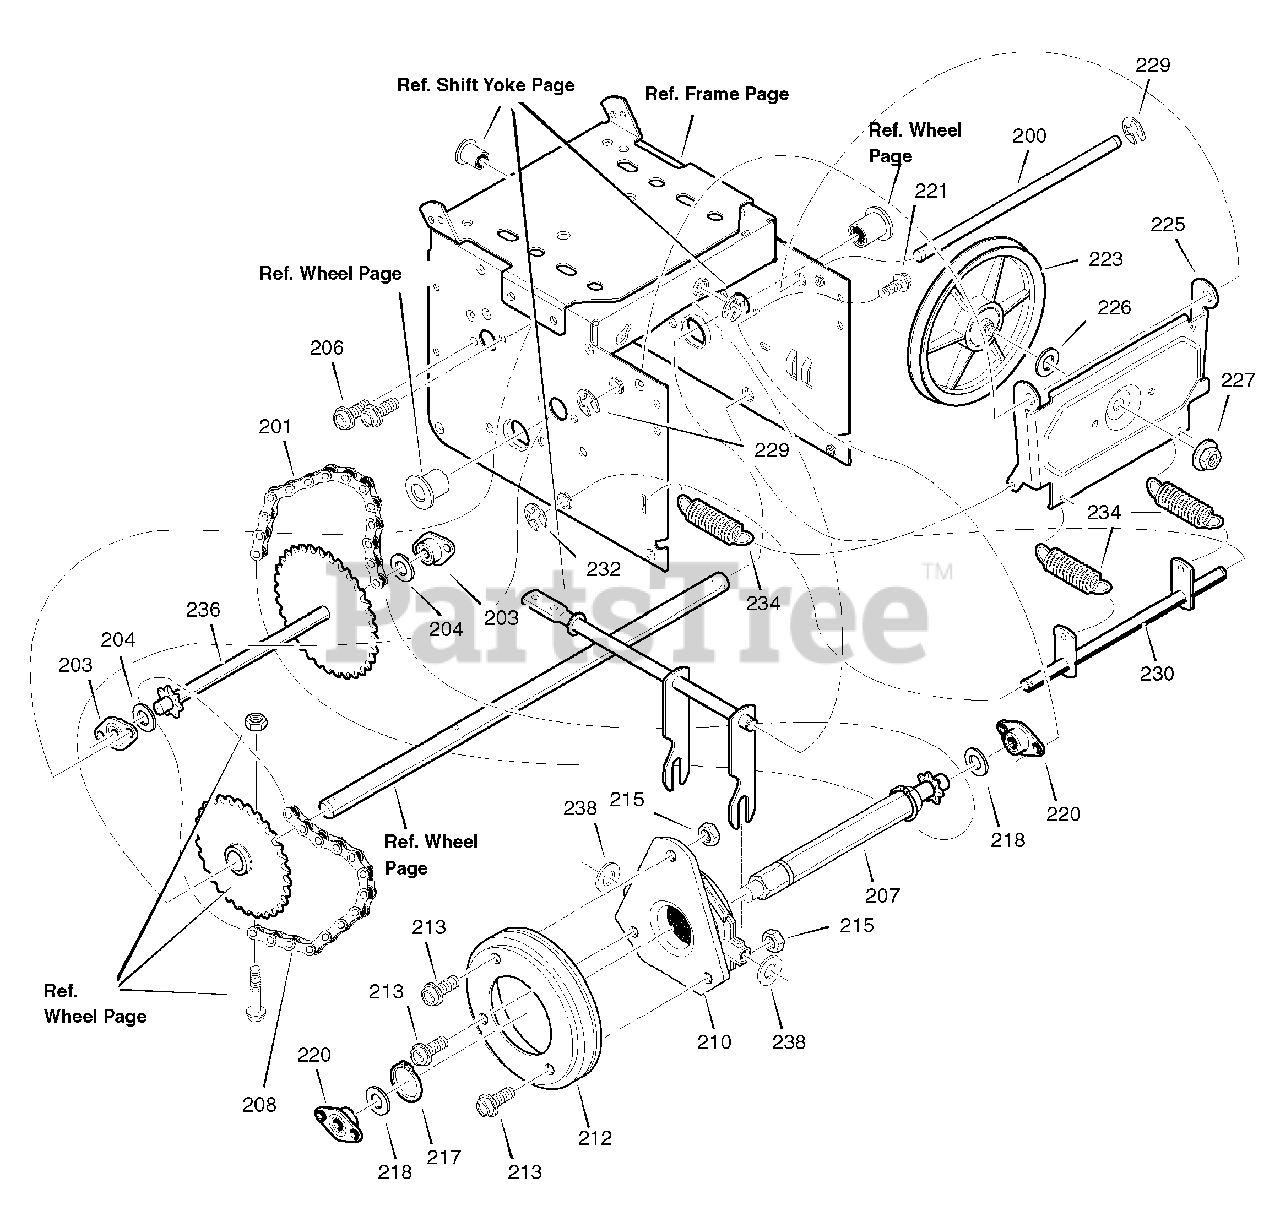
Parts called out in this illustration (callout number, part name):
200	LF AXLE, SWING PLATE YZ
201	CHAIN, ROLLER #420x19.00
203	BEARING AND RETAINER, ASSY
204	WASHER
206	SCREW, TAP 5/16-18 x 0.5
207	ASSY, HEX SHAFT
208	CHAIN, ROLLER #420x18.00 LG
210	BEARING, TRUNION CLUTCH R
212	WHEEL, FRICTION DISC
213	BOLT
215	NUT, KEPS HEX 1/4-20
217	RING, RETEXT
218	WASHER
220	BEARING AND RETAINER, ASSY
221	SCREW, TAP 5/16-18 x .5
223	FRICTION PULLY
225	LF PLATE, SWINGING YZ
226	SPACER, FRICTION PULLEY
227	NUT, FLANGE LOCK 3/8-24
229	RETAINER, RING
230	ASSY, LF SPRING LINK YZ
232	RETAINER, RING
234	SPRING, EXTENSION
236	WLD, INTERMED SPROCKET 33T/7
238	WASHER, FLAT
